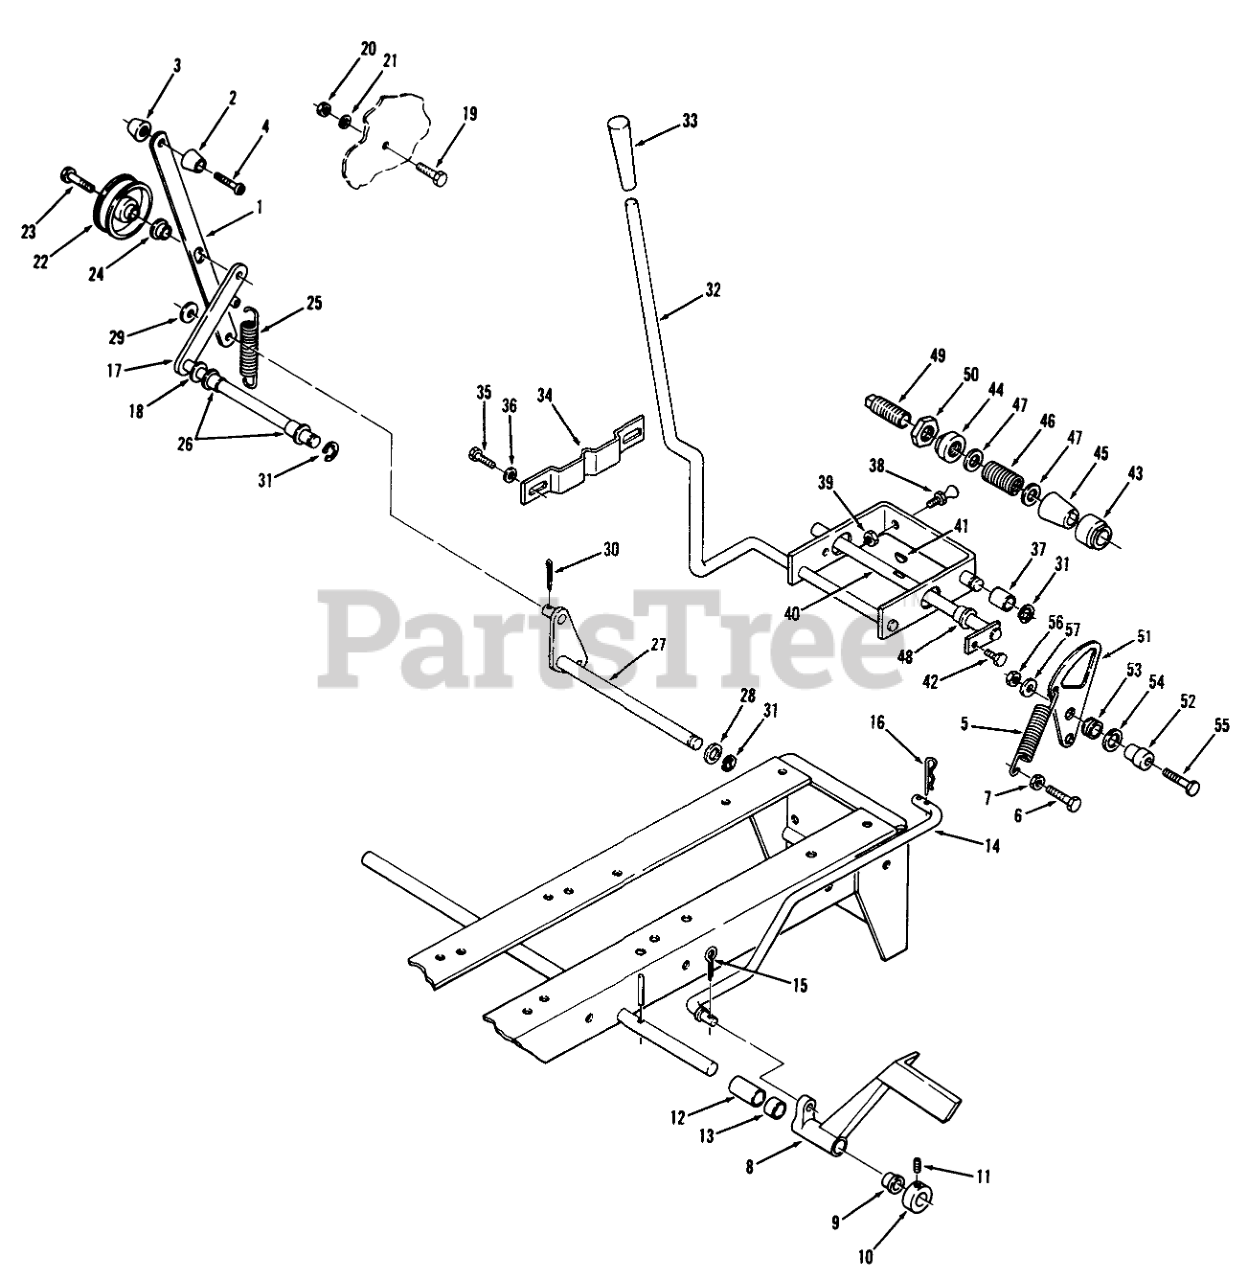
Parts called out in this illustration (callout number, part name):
1	HANDLE R (NS)
2	KNOB
3	KNOB
4	BOLT-4
5	Spring
6	Bolt
7	Nut
8	PEDAL R
9	BUSHING
10	Collar
11	SCREW-SET
12	SPACER
13	Spacer
14	Gasket
17	Idler Arm
18	Washer
19	Bolt
20	Nut
21	Washer
22	Idler Pulley
23	HEX HD CAP SCREW
24	SPACER-BRAKE LINK
25	SPRING-EXTENSION
26	BUSHING-FLANGED
27	ever Brake
28	Washer
29	Washer
30	Cotter Pin
31	E Ring
32	Cam Control
33	KNOB
34	SPRING-DETENT
35	SCREW
36	WASHER 5/16 SAE
37	BEARING-CAM RETURN
38	PIN
39	Nut
40	Cam Pivot Rod
41	WOODRUFF KEY
42	SCREW
43	FRICTION COLLAR
44	COLLAR BRKT PIVOT
45	FRICTION CONE
46	SPRING FRICTION
47	Washer
48	BUSHING-FLANGED
49	Collar Friction
51	Cam Plate
52	Spacer
53	NYLINER BUSHING
54	SHIM-WASHER
55	Bolt
56	Nut
57	Washer
